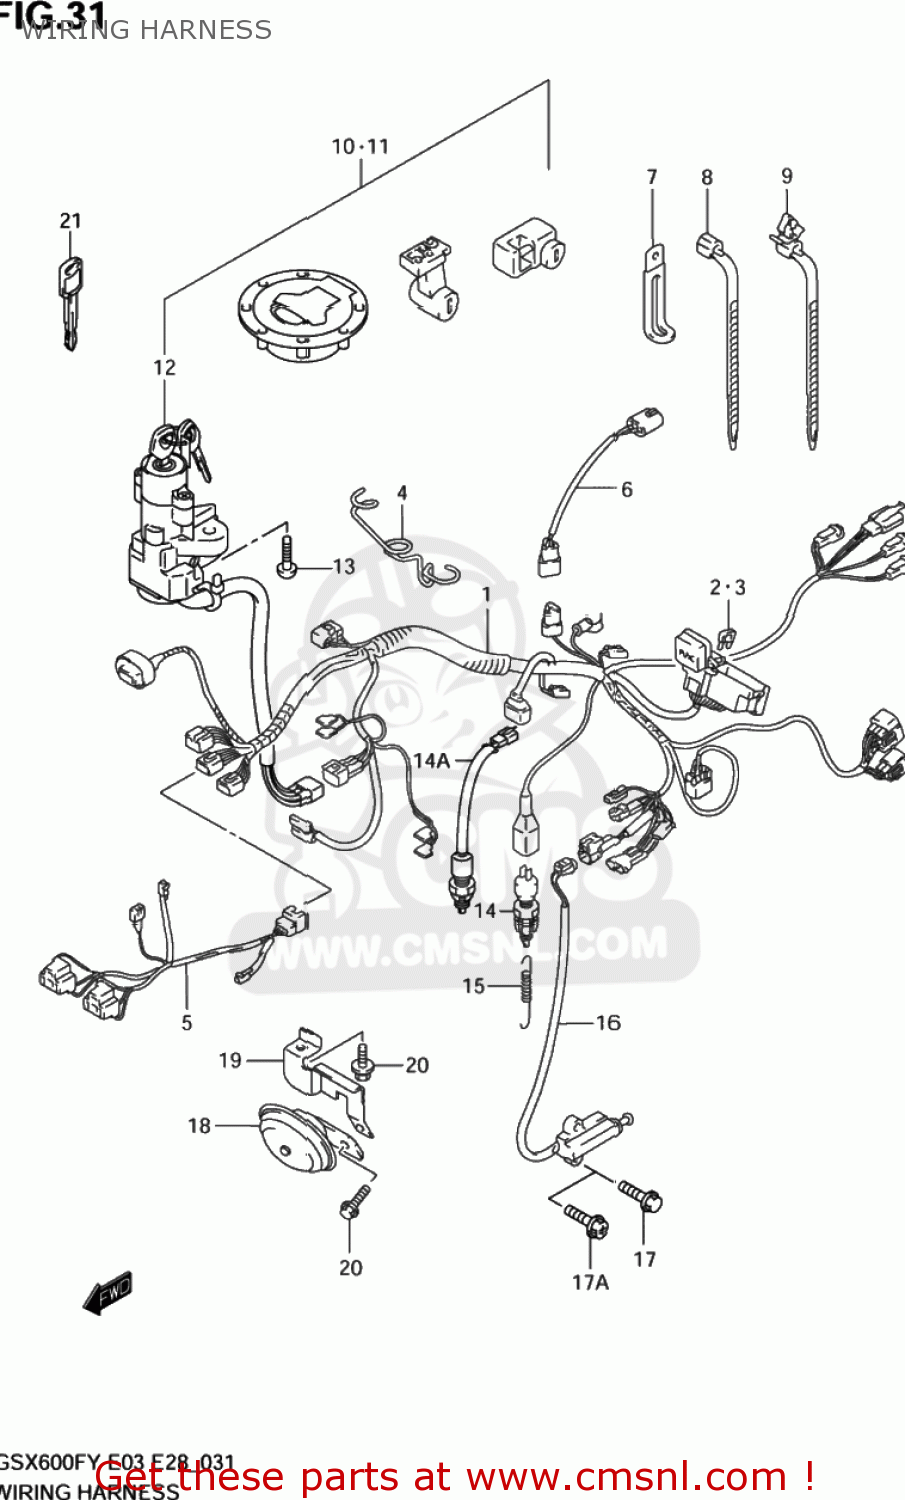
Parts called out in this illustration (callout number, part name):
1	HARNESS,WIRING
2	FUSE(10A)
3	FUSE(15A)
4	GUIDE,WIRING HARNESS
5	HARNESS,WIRING NO.2
6	WIRE,LEAD
7	CLAMP(L:135)
8	CLAMP(L:165)
9	CLAMP
10	LOCK SET
11	LOCK SET
12	LOCK ASSY,STEERING
13	BOLT(8X20)
14	SWITCH ASSY,STOP LAMP
14A	SWITCH ASSY,STOP LAMP
15	SPRING
16	SWITCH ASSY,SIDE STAND
17	BOLT
17A	SCREW
18	HORN ASSY
19	BRACKET,HORN
20	BOLT
21	KEY,BLANK
